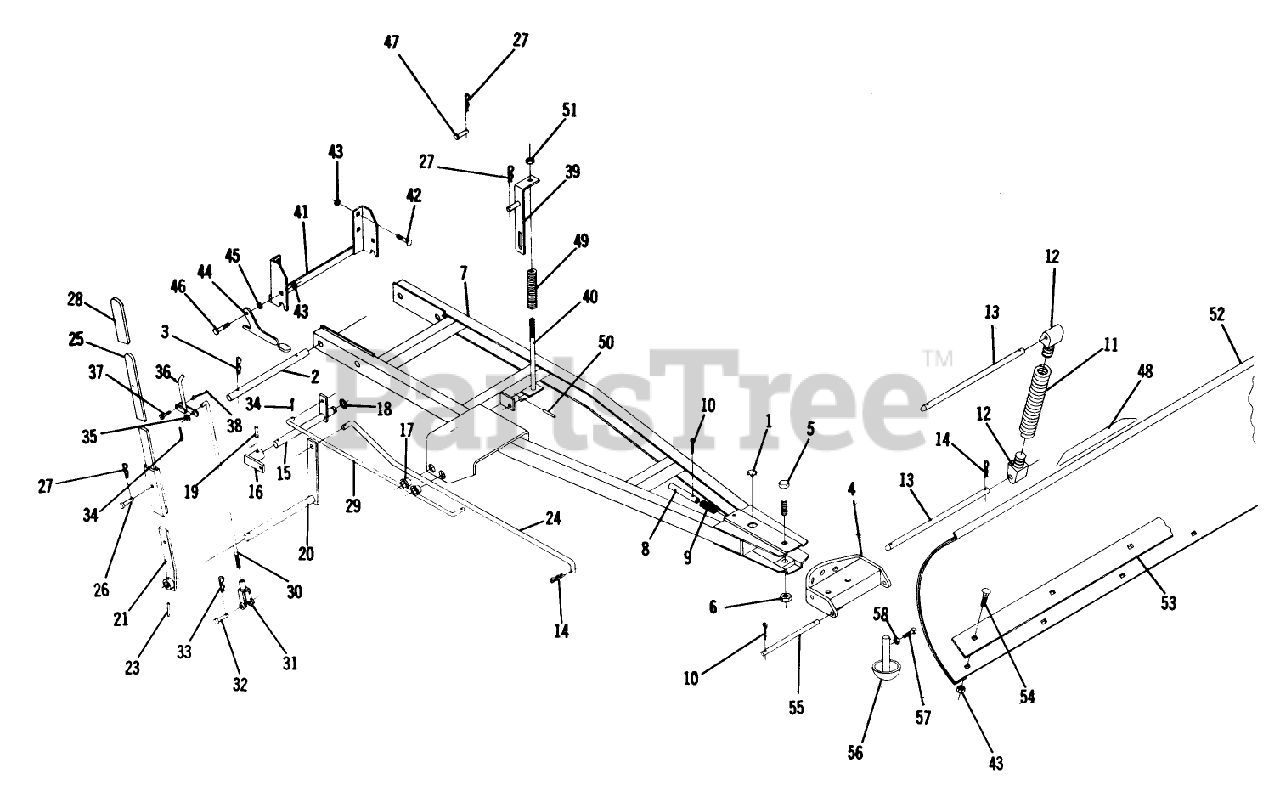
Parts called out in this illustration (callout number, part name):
1	PLUG
2	Mounting Shaft
3	Hairpin
4	Sector and Channel
5	Bolt
6	Nut
7	Frame Assembly
8	Index Pin
9	SPRING-COMPRESSION
11	Spring
12	Lug
13	ROD-TRIP RETURN
14	Hairpin
15	Bushing
16	Sat Collar
17	BUSHING
18	Snap Ring
19	SPIROL PIN 3/8X1 3/4
19	Washer
20	Assembly-Blade Index Arm
21	Assembly-Handle Bar
22	Nut
23	SPIROL PIN 3/8X1 1/2
24	Blade Control Rod
25	HANDLE ASM
26	Pin-Clevis
27	Hairpin Cotter
28	GRIP
29	ROD LOWER INDEX
30	ROD UPPER INDEX
32	Pin
34	Cotter Pin
36	Assembly Index Lever
37	Bolt
38	Nut
39	Assembly-Lift Bar
40	Assembly Lift Rod
41	Bracket
42	Bolt-Carriage
43	NUT
44	Latch Hitch
45	Washer
46	BOLT
48	DECAL-WHEEL HORSE
49	SPRING
50	Spirol Pin
51	Nut
52	Blade Assembly
53	PLATE-BLADE EDGE
54	Bolt-Carriage
55	ROD-LOWER
56	SKID SHOE ASSY R
57	Screw-Set
57	Caution Decal
